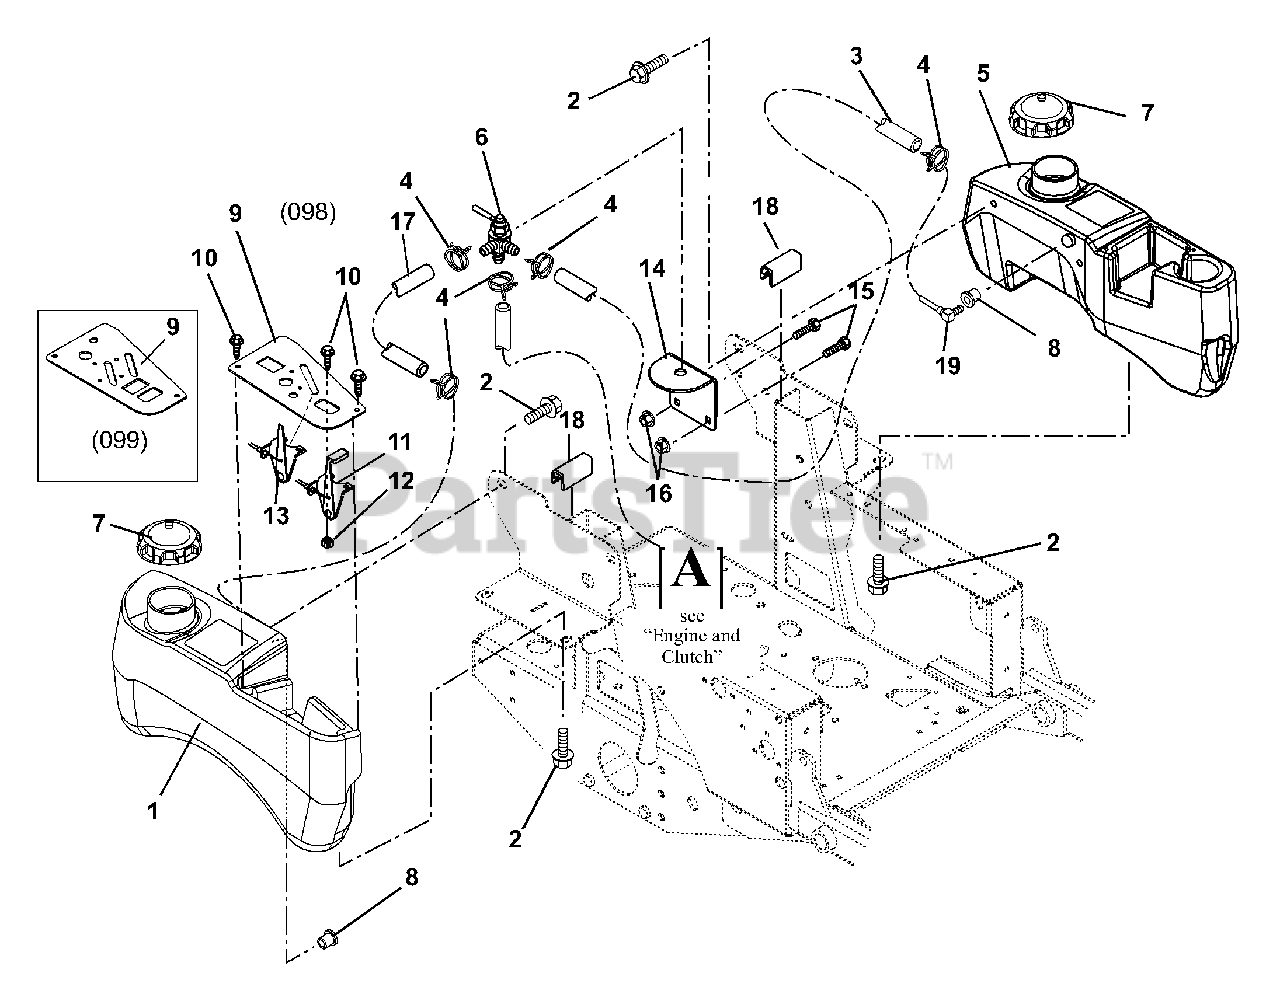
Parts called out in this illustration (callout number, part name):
1	TANK, FUEL RH W/O HOSE
2	BOLT, SEMS .31-18 X .62
3	GAS LINE-BULK 1/4" I.D.
4	CLAMP-HOSE WIRE .490/.510X.116
5	TANK, LH FUEL CZ W/O HOSE
6	VALVE, FUEL
7	CAP - FUEL
8	BSHG-FLG .375 X 1.062 X .625 R
8	GROMMET, DAPCO VITON #12240
9	PANEL, CONTROL
10	@SCR-MCH 10-24X.50 HWH YWZC
11	CABLE, THROTTLE-CHOKE
12	@NUT-LK-NYL 10-24 W/INSRT YWZC
13	CABLE, CHOKE
13	CABLE, CHOKE/THROTTLE
14	BRKT, FUEL VALVE MNTG
15	@BLT-RDHDSQNK .31-18X.75 G5YZ
16	@NUT-LK-NYL-FLG .31-18 YWZC
17	GAS LINE-BULK 1/4" I.D.
18	STRIP, COWL
19	FITTING, TANK ELBOW .31 HOSE
